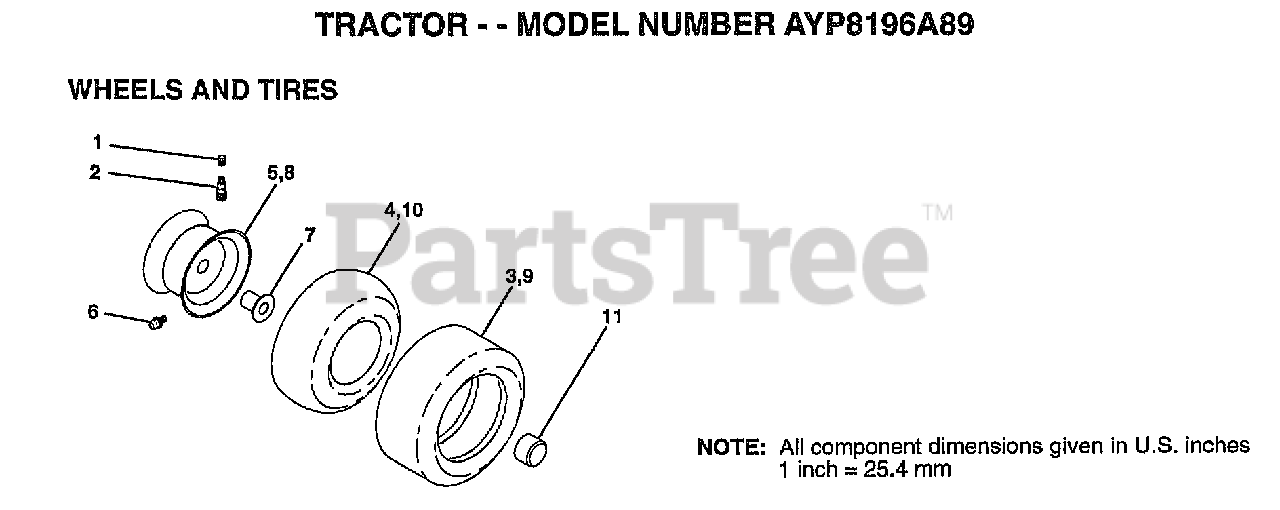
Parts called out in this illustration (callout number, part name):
1	VALVE CAP
2	VALVE STEM LT
4	TUBE.5.3/4.5/6
5	"RIM ASM 8"" FRT"
6	FITTING LT
7	"FLANGE, BEARING"
8	RIM.REAR.
10	TUBE.23X8/10-12
11	HUB CAP
